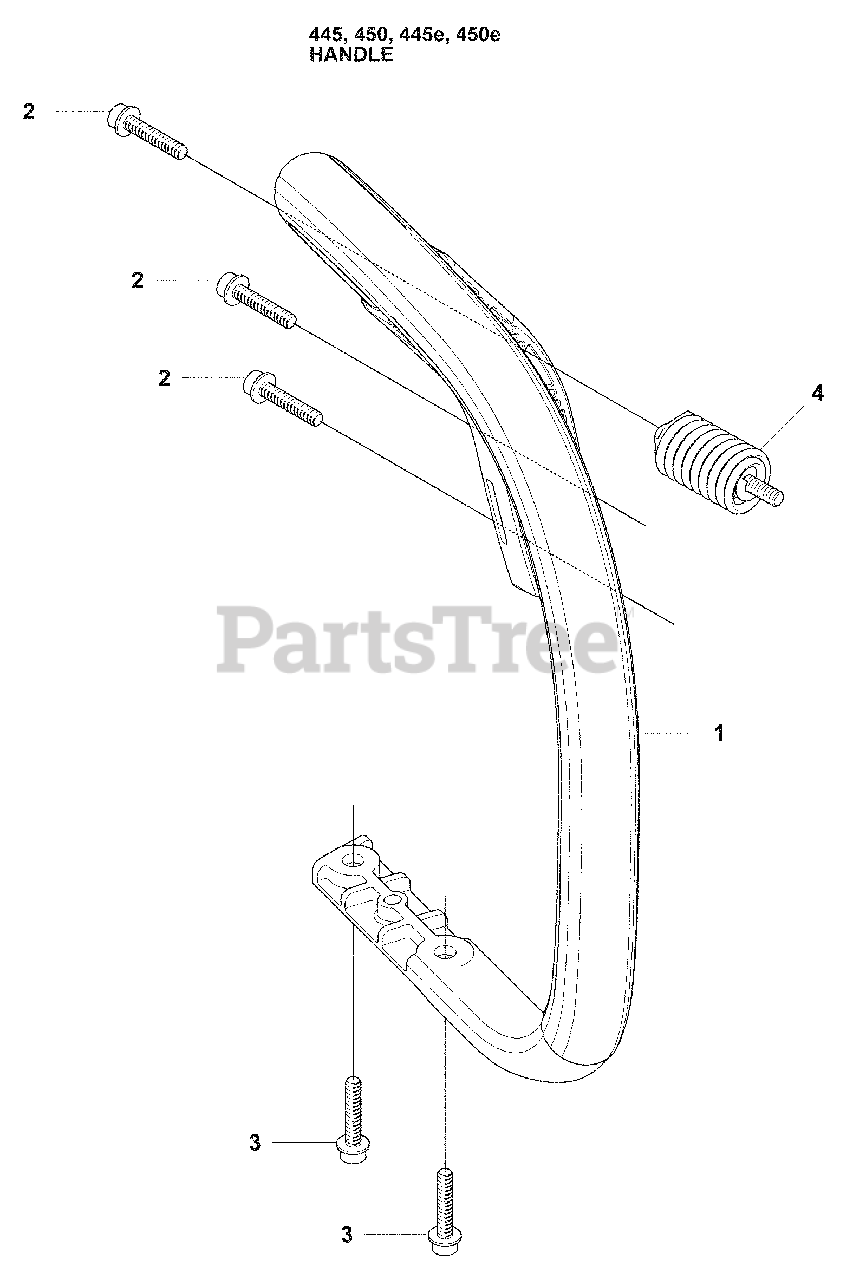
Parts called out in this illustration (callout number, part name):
1	Front Handle
2	Screw, 3 X 25 IHSCFT
3	Screw, STC 6Sf St6.3
4	Insulator
